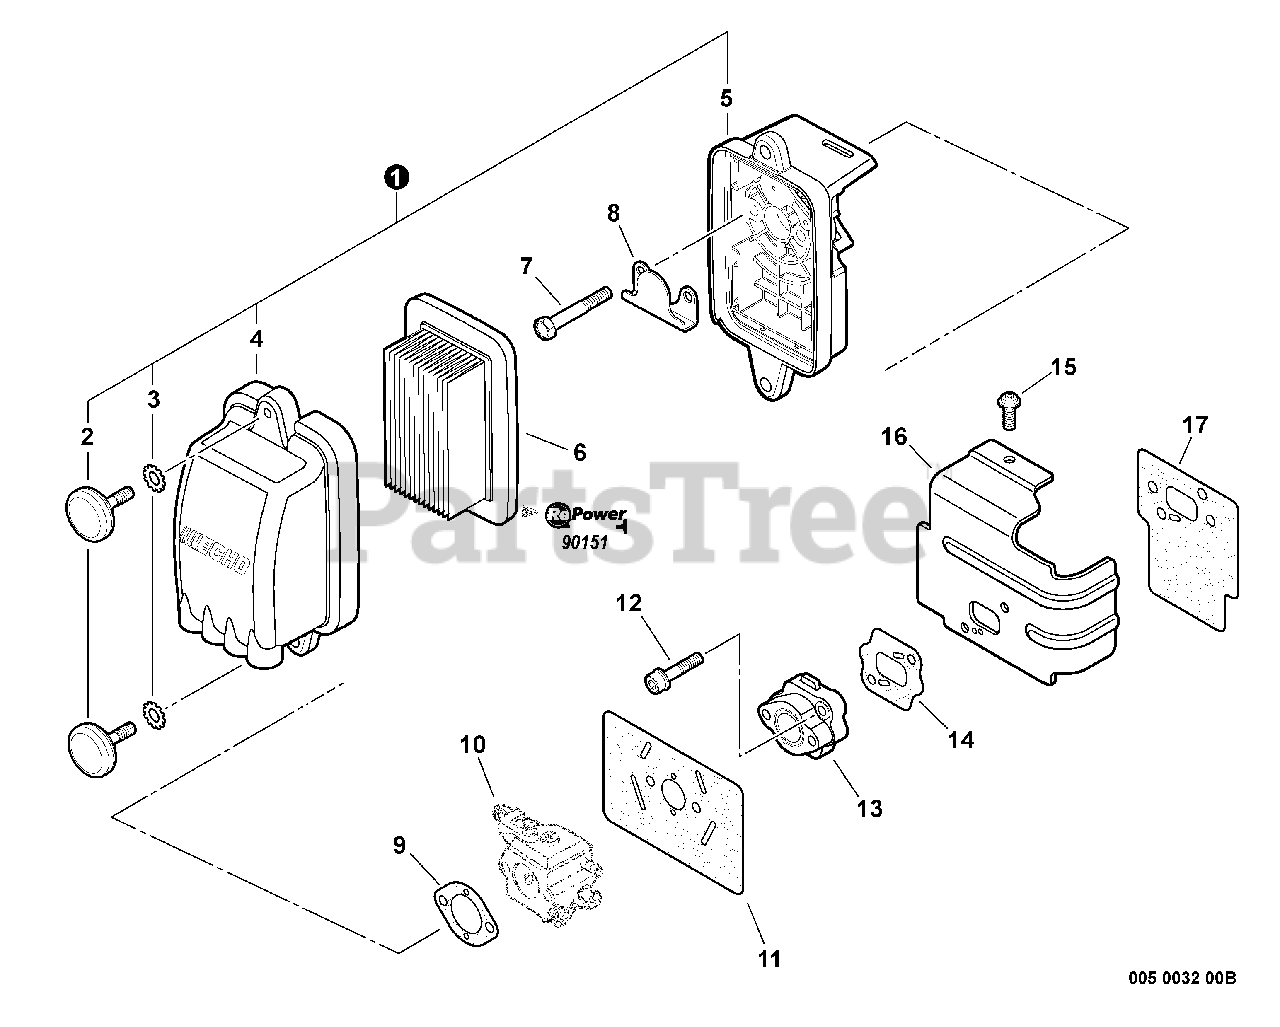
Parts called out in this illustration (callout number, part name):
1	AIR CLEANER KIT
2	THUMBSCREW
3	LOCKWASHER
4	COVER, AIR FILTER
5	AIR FILTER CASE ASSY
6	FILTER, AIR
7	SCREW - 5X60
8	PLATE, PREVENT
9	GASKET, INTAKE
10	CARBURETOR
11	GASKET, INTAKE
12	SCREW - 5X25
13	INSULATOR, INTAKE
14	GASKET, INTAKE
15	SCREW - 5X10
16	COVER, CYLINDER - INTAKE
17	SHIELD, INTAKE
18	RePower TUNE-UP KIT
